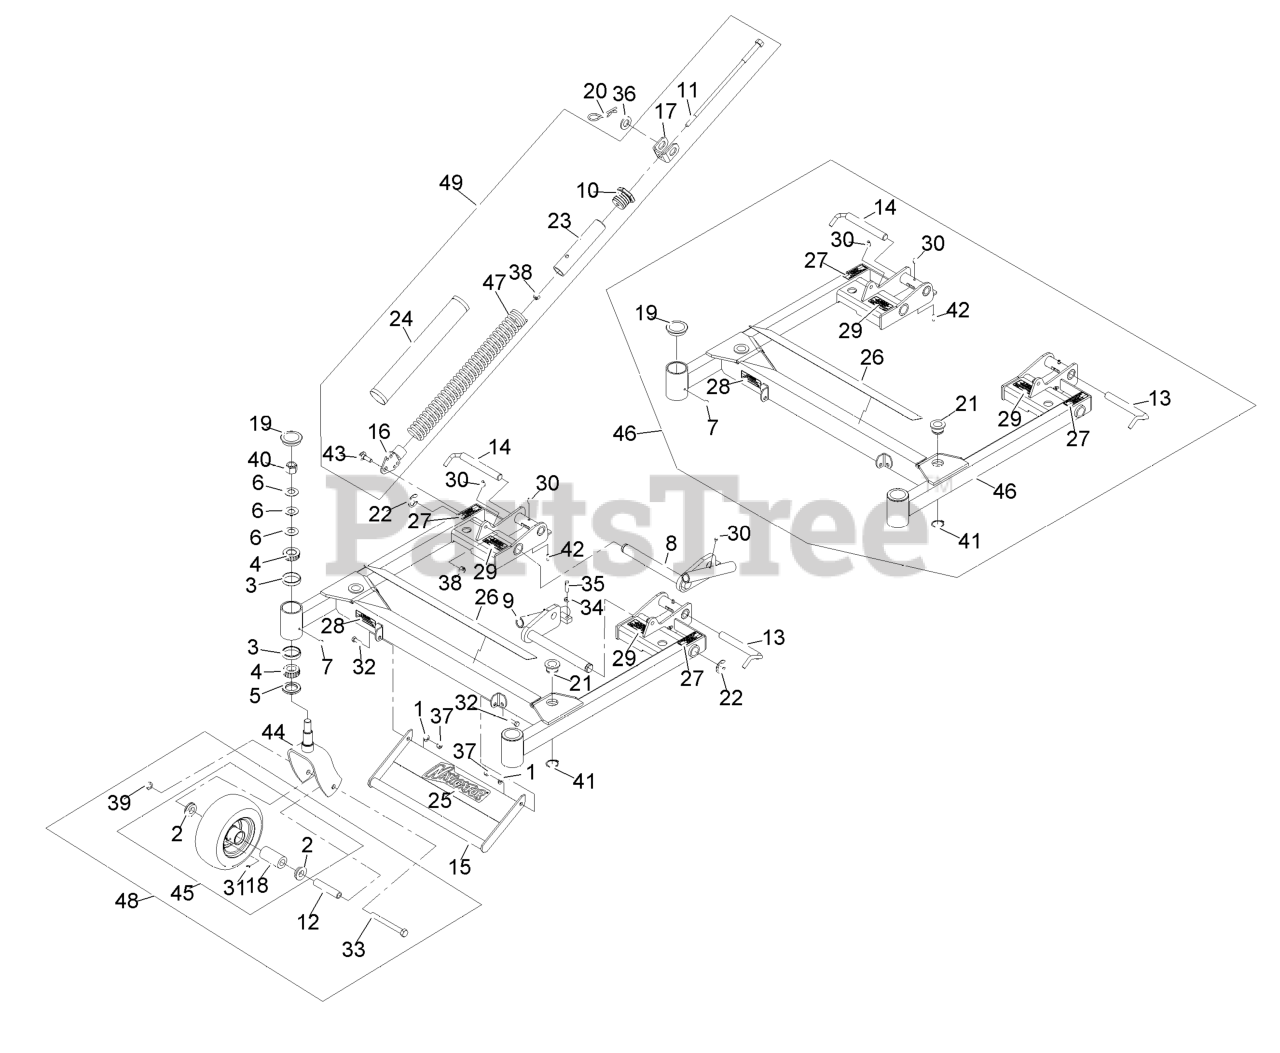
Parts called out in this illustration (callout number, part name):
1	WASHER-SPRING
2	BUSHING
3	CUP-BEARING
4	Cone-Bearing Tapered Roller
5	SEAL-GREASE
6	WASHER-BELLVILLE
8	PIVOT-DECK, RH
9	PIVOT-DECK, LH
10	PLUG-ADJUSTER, SPRING
11	SHAFT-ADJUSTMENT, SPRING
12	SPACER-CASTER, FRONT
13	LOCK-DECK, LH
14	LOCK-DECK, RH
15	ASM,DECK LIFT HANDLE W/DE
16	TENSIONER-SPRING
17	MOUNT-LIFT ASSIST, DECK
18	BEARING-ROLLER, STRAIGHT
19	CAP-GREASE
20	PIN-CUT HEIGHT
21	BUSHING-SUPPORT, DECK
22	RING-SNAP
23	SPRING-TUBE
24	COVER-SPRING, DECK
25	DECAL,NAVIGATOR MODEL
26	PAD-ANTI SKID
27	DECAL-FOLDING DECK
28	DECAL-DANGER
29	DECAL-SPRING
30	FITTING-GREASE
31	FITTING-GREASE
32	SCREW-HH
33	SCREW-HH
34	NUT-JAM
35	SCREW-SET, SQH
36	WASHER-FLAT
37	NUT-LOCK, NI
38	NUT-LOCK, NI
39	NUT-HEX
40	NUT-LOCK, NI
41	RING-RETAINING
42	PIN-SPRING
43	SCREW-SHOULDER, HWH
44	FORK-CASTER
45	ASM,WHEEL,TIRE & BRGS 8X3
46	DECK SUPPORT ASM
47	SPRING-EXTENSION
48	ASM,FF CASTER WHEEL W/AXL
49	ASM,LIFT AST SPRING (42")
